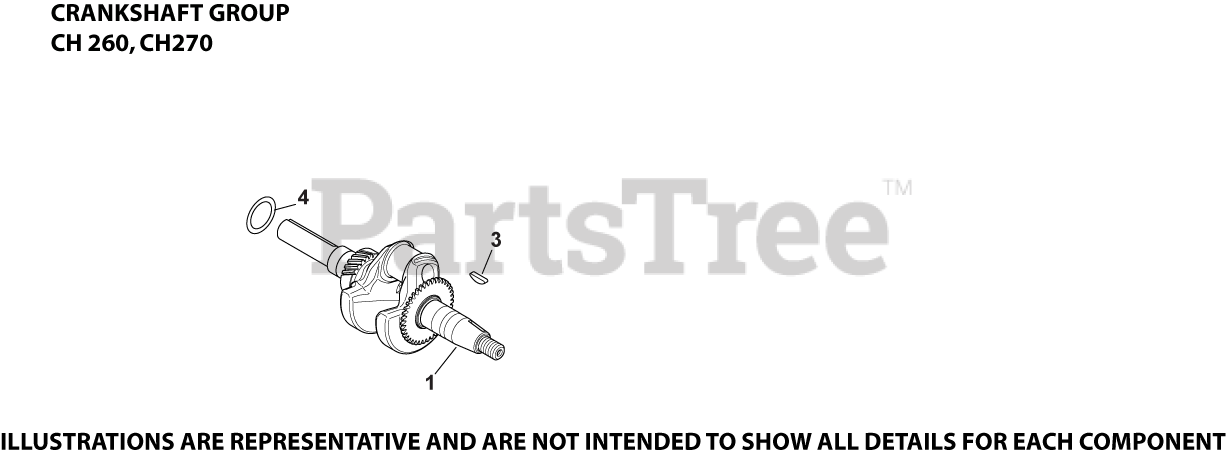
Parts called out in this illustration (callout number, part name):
1	CRANKSHAFT ASSEMBLY
3	KEY, FLYWHEEL
4	KIT, THRUST SHIM
